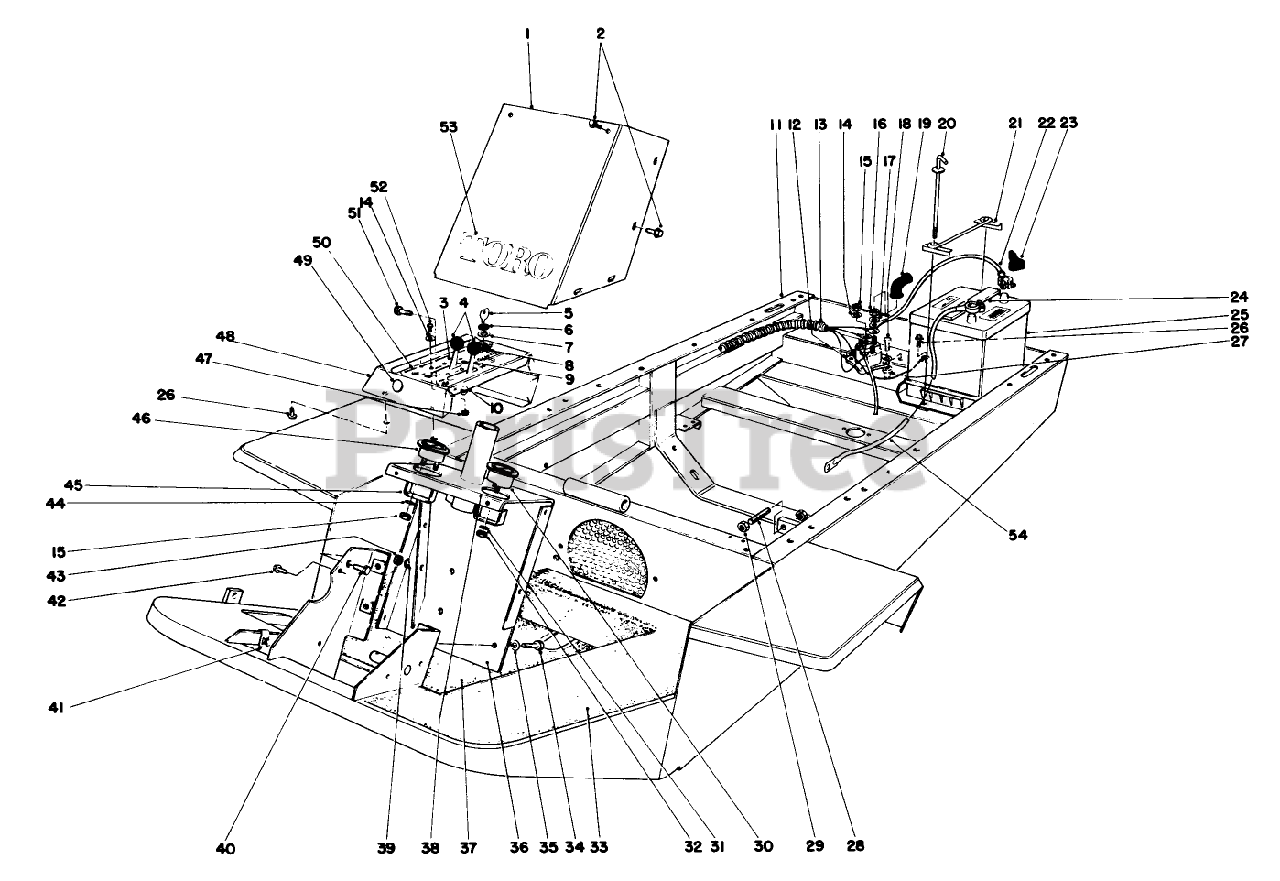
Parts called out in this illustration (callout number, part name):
1	Tower Cover
2	SCREW-HHFTF
3	CHOKE CONTROL
5	Key
6	NUT-HH
7	WASHER-TOOTH, INTERNAL
8	Starter Switch (Incl. Ref. #5-7)
9	THROTTLE CONTROL
10	WASHER-FLAT
11	Frame
12	SOLENOID
13	WIRE HARNESS
14	WASHER-LOCK
15	NUT-HEX
16	NUT-JAM, BRASS
17	WASHER-LOCK
18	SCREW-HH
19	BATTERY BOOT
20	BATTERY BOLT WA B
21	BATTERY HOLD DOWN WA
22	BATT/SOLENOID WIRE
23	BOOT-CABLE, BATTERY
24	PUSH-ON BATTERY CAP
25	Battery
26	SCREW-THD FRM,HWH
27	NUT-INSERT
28	STOP PIN PP
29	NUT-JAM
30	HOUR METER
31	WASHER-LOCK, INT
32	NUT-HEX
33	NON SKID (TUNNEL)
34	SCREW-HH
35	WASHER-LOCK
36	Steering Post
37	NON-SKID-FLOOR
38	INSTRUCTION DECAL
39	WASHER-LOCK
40	SCREW-HH
41	SPEED NUT
42	SCREW-HWH
43	NUT-HEX
44	WASHER-FLAT
45	MTG CLAMP F/W GUAGE
46	AMMETER GAUGE ASSY
47	NUT-HEX
48	Instrument Panel
49	Domed Plug
50	Decal-Instrument Panel
51	SCREW-HH
52	10-24 X 5/8 PAN HD MS
53	DECAL
54	BATTERY GROUND WIRE
